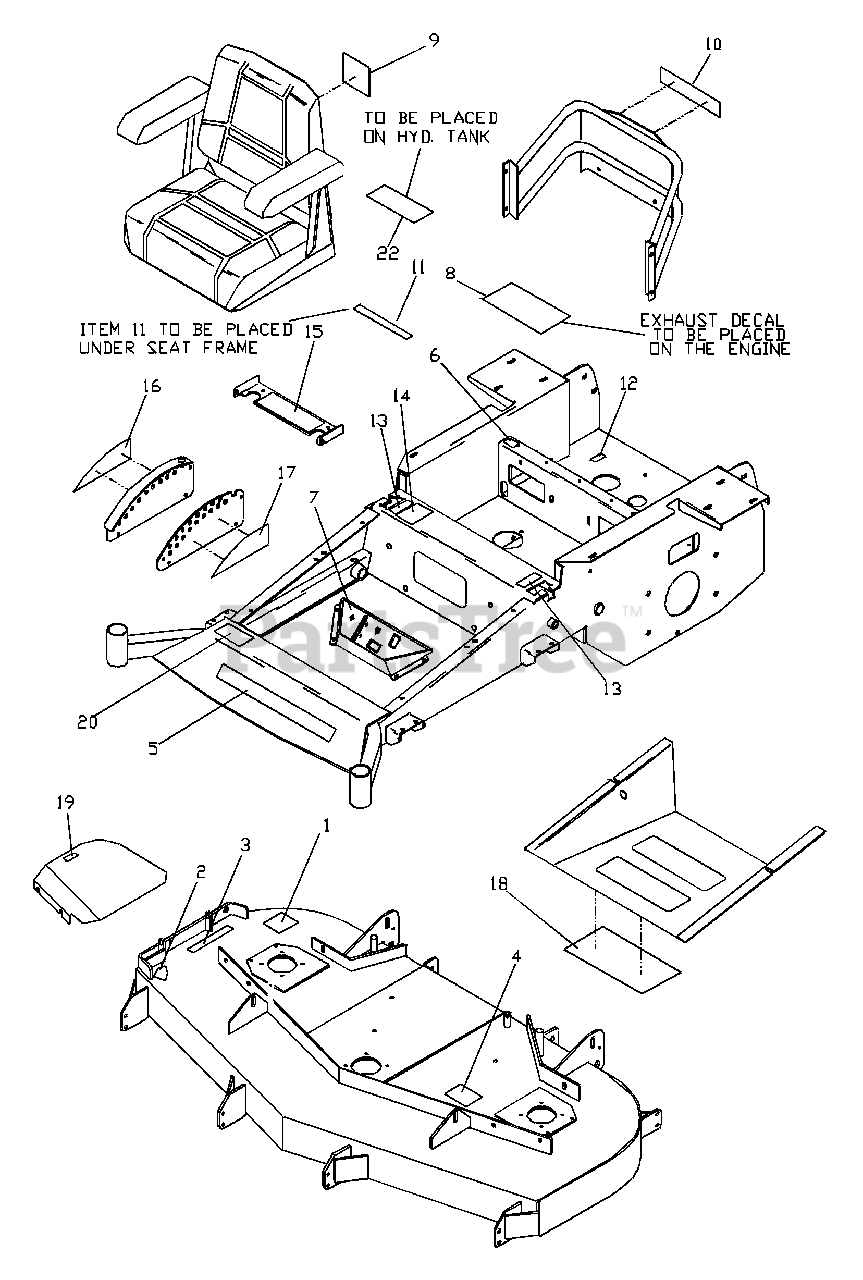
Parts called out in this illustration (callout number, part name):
1	DECAL, ANTI SCALP
2	DECAL, DANGER
3	DECAL, WARNING
4	DECAL, BELT ROUTING
5	DECAL, HUSQVARNA
6	DECAL, FUEL VALVE
7	DECAL, CONSOLE
8	DECAL, EXHAUST
9	DECAL, CROWN
10	DECAL, HUSQVARNA
11	DECAL, BATTERY
12	DECAL, PROP 65
13	DECAL, MOTION CONTROL
14	DECAL, THROWN OBJECTS
15	DECAL, WARNING
16	DECAL, HEIGHT
17	DECAL, HEIGHT
18	DECAL, SERVICE
19	DECAL, NO STEP
20	DECAL, NASCAR
21	DECAL, 5223
21	DECAL, 5223L
21	DECAL, 5225
21	DECAL, 6125
22	DECAL, MOBIL 1
